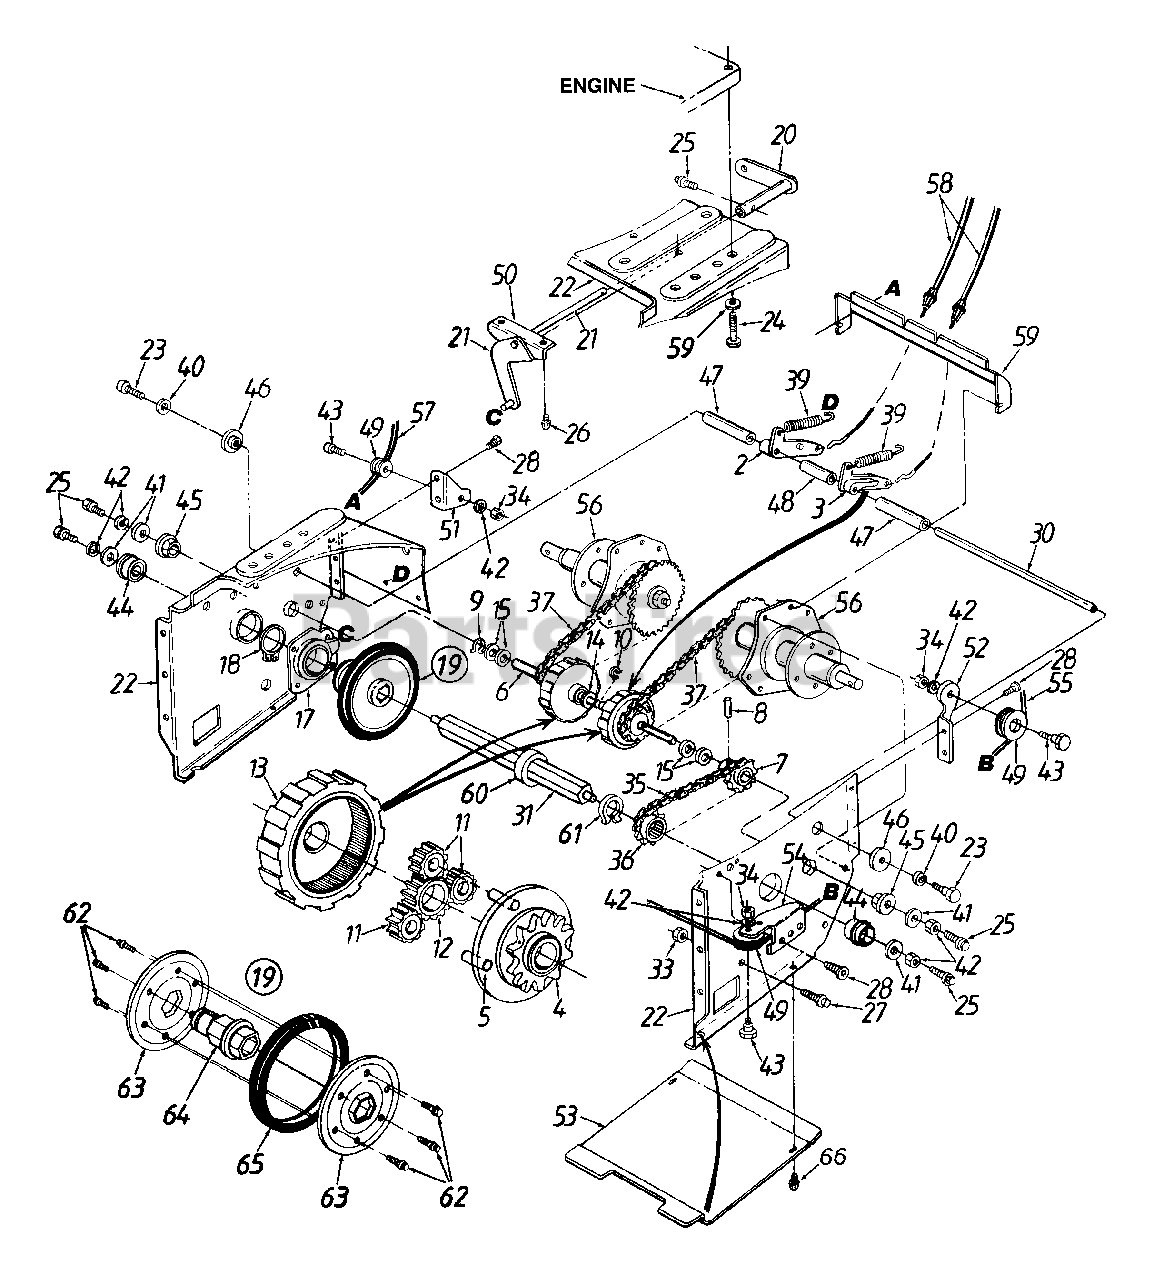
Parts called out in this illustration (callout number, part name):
2	R.H. Dog Ass'y.
3	L.H. Dog Ass'y.
4	Carrier
5	5/16" Dowel Pin
6	Drive Shaft
7	12 Tooth Sprocket
8	Spring Pin 3/16" Dia. x 1" Lg.
9	Snap Ring .56" Dia.
10	Snap Ring .625" Shaft
11	12 Tooth Gear
12	18 Tooth Gear
13	Ring Gear
14	Fl-Wash. 5/8" I.D. x 1" O.D.
15	Fl-Wash. .57" I.D. x 1.12" O.D.
17	Friction Wheel Brg. Ass'y.
18	Retaining Ring 1.375" Dia. Shaft
19	Friction Wheel
20	Shift Arm Ass'y.
21	Shift Rod Ass'y.
23	Hex Bolt 5/16-18 x .75" Lg.
24	Hex L-Wash. TT-Tap Scr. 3/8-16 x 1.25" Lg.
25	Hex TT-Tap Scr. 1/4-20 x .75" Lg.
26	Hex Wash. Hd. Tap Scr. 1/4-20 x .38" Lg.
27	Hex Wash. TT-Tap Scr. 1/4-20 x 1" Lg.
28	Torx Mach. AB-Tap Scr. 1/4 x .62" Lg.
30	Actuator Shaft
31	Drive Shaft
33	Hex Nut 1/4-20 Thd.
34	Hex Jam Nut 1/4-20 Thd.
35	#420 Chain - 1/2 Pitch x 30 Links (Endless)
36	11 Tooth Sprocket
37	#420 Chain - 32 Links (Endless)
39	Extension Spring 2.03" Lg.
40	L-Wash. 5/16" I.D.
41	Fl-Wash. 1/4" I.D. x .93" O.D.
42	L-Wash. 1/4" I.D.
43	Shld. Bolt 5/16" Dia. x .35" Lg.
44	Ball Brg. w/Snap Ring
45	Hex Flange Bearing
46	Shld. Spacer .5" Dia. x .27" Lg.
47	Split Shld. Spacer 2.69" Lg.
48	Split Shld. Spacer 1.77" Lg.
49	Cable Roller
55	Auger Clutch Cable
56	Track Hub Ass'y.
57	Drive Clutch Cable
58	Track Steer Cable w/Trigger
59	Fl-Wash. .406" I.D. x 1" O.D.
60	Spacer 1.02" I.D. x 1.25" O.D.
61	Snap Ring
62	Hex Wash. Hd. TT-Tap Scr. 1/4-20 x .5" Lg.
63	Friction Plate
64	Friction Wheel Hub
65	Friction Wheel Rubber
66	Hex Wash. Tap Scr. .38" Lg.
